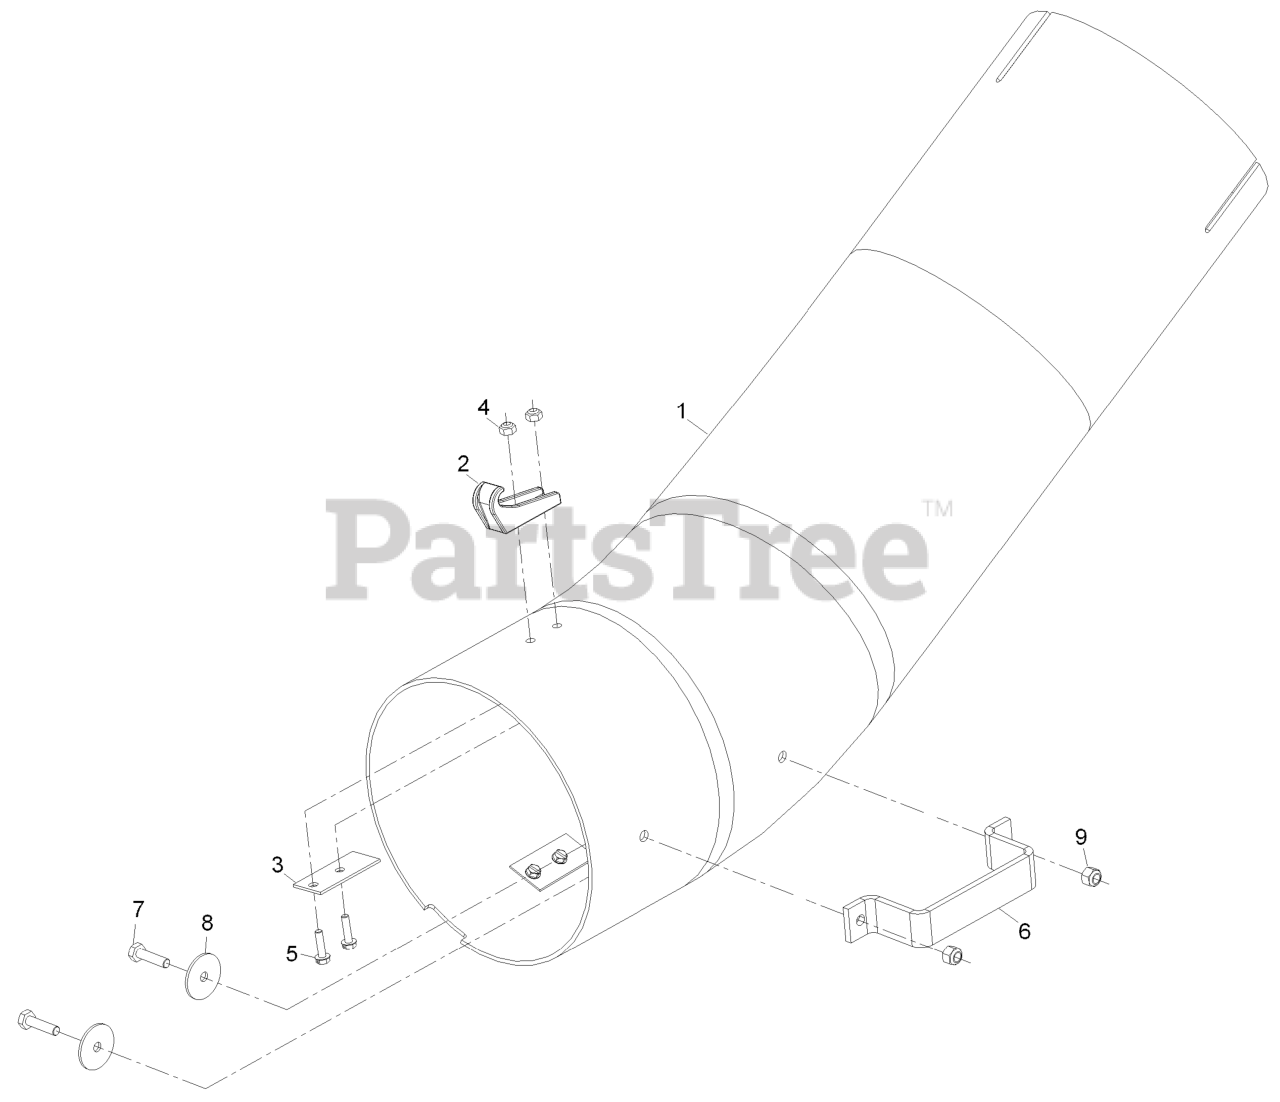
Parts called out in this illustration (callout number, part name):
2	Latch-Catch
3	Plate-Backing
4	Tube, Lower
5	Screw-HH 1/4-20 X 1
7	Nut-Nyloc #10-24
8	Nut-Nyloc 1/4-20
9	Screw-HWH #10-24 X 3/4
